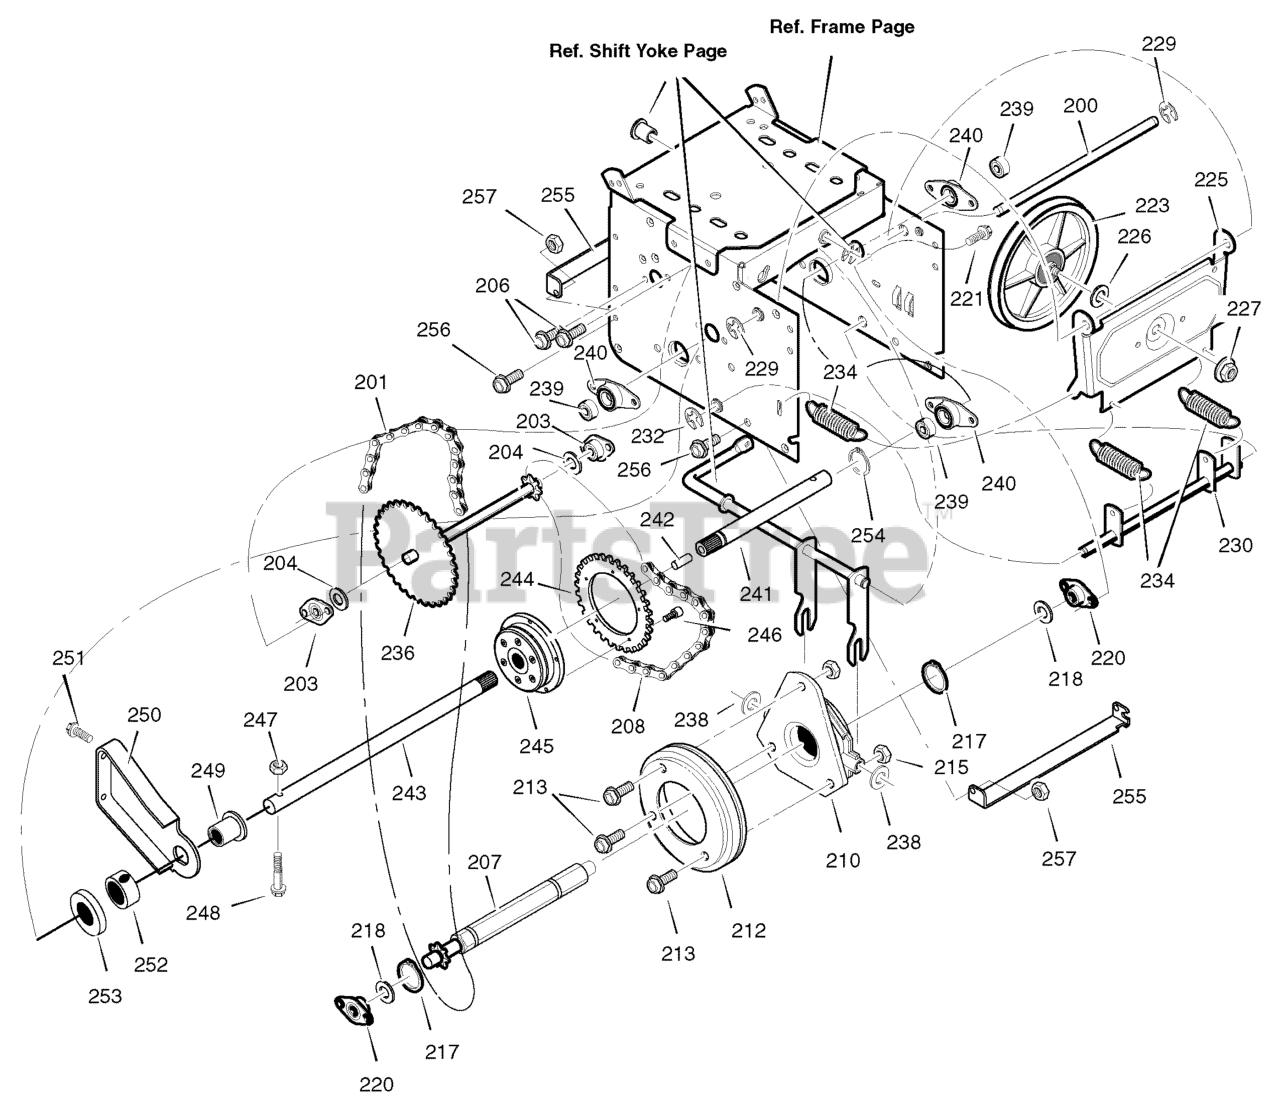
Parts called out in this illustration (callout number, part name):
200	LF AXLE, SWING PLATE YZ
201	CHAIN, ROLLER #420x19.00
203	BEARING AND RETAINER, ASSY
204	WASHER
206	SCREW, TAP 5/16-18x0.5
207	ASSY, HEX SHAFT
208	CHAIN, ROLLER #420x18.00 LG
210	BEARING, TRUNION CLUTCH R
212	WHEEL, FRICTION DISC
213	BOLT
215	NUT, KEPS HEX 1/4-20
217	RING, RETEXT
218	WASHER
220	BEARING AND RETAINER, ASSY
221	SCREW, TAP 5/16-18 x .5
223	FRICTION PULLY
225	LF PLATE, SWINGING YZ
226	SPACER, FRICTION PULLEY
227	NUT, FLANGE LOCK 3/8-24
229	RETAINER, RING
230	ASSEMBLY, SPRING LINK STEERABLE
232	RETAINER, RING
234	SPRING, EXTENSION
236	SPROCKET SET 33T/7
238	WASHER, FLAT
239	BEARING, BALL
240	RETAINER, BEARING
241	AXLE, LEFT
242	PIN, AXLE
243	AXLE AND BUSHING, RIGHT
244	SPROCKET
245	CLUTCH, AUTO LOCK
248	BOLT
249	BEARING, AXLE
250	BRACKET, AXLE SUPPORT
251	SCREW
252	COLLAR, LOCKING
253	WASHER
254	RETAINER, RING
255	BRACKET, SUPPORT
256	BOLT
